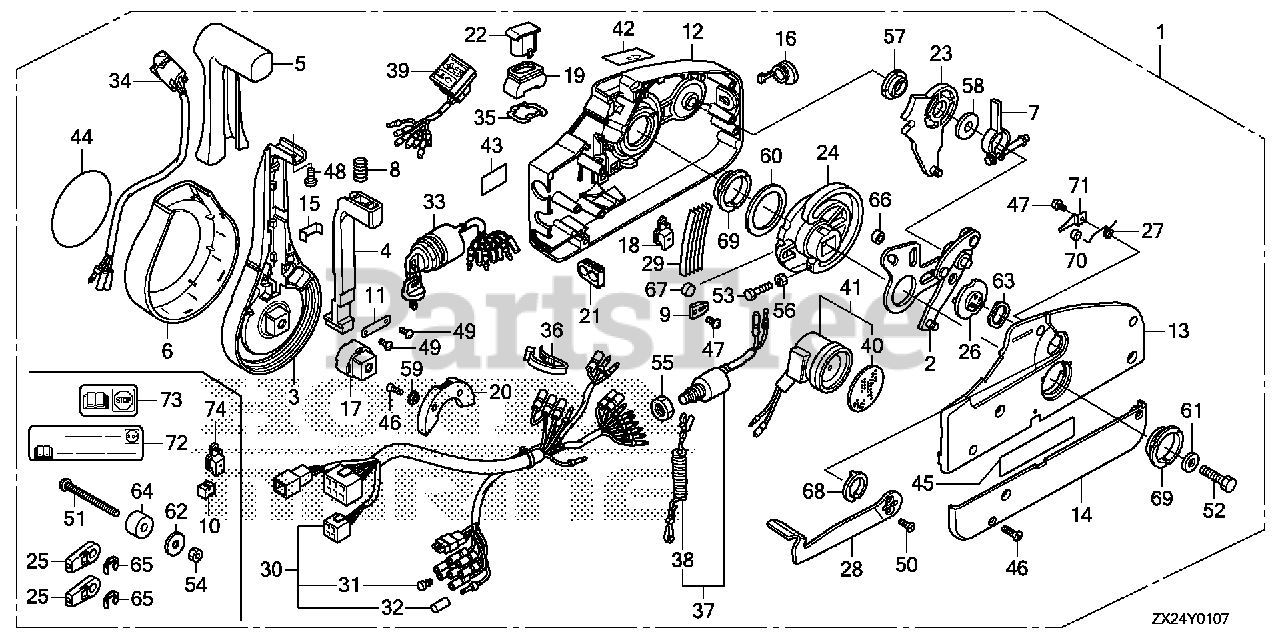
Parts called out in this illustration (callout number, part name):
1	BOX ASSY., REMOTE CONTROL (NHK MEC)
1	BOX ASSY., REMOTE CONTROL (TROLLING CONTROL)(NHK MEC)
2	PLATE ASSY.
3	LEVER, HAND
4	ARM, NEUTRAL LOCK
5	GRIP
6	COVER, LEVER
7	ARM ASSY., BRAKE
8	SPRING (2)
9	CLIP, DETENT
10	SPACER (1) (LOOSE PARTS)
11	BRACKET
12	HOUSING, FR.
13	HOUSING, RR.
14	PANEL, BACK
15	BRACKET, WIRE CLAMP
16	CAP, RUBBER
17	ADJUSTER
18	COVER, POWER TRIM-TILT WIRE
19	SEAL, RUBBER
20	HOLDER, NEUTRAL LOCK
21	GROMMET, WIRE (14)
22	CAP, TROLLING CONTROL SWITCH BLANK
23	GEAR ASSY., SHIFT
24	GEAR, DRIVE
25	TERMINAL, CABLE (LOOSE PARTS)
26	DRUM ASSY., FREE THROTTLE
27	SPRING (1)
28	LEVER, FREE THROTTLE
29	SPRING, DETENT
30	CABLE ASSY., REMOTE CONTROL (B)
31	PLUG, CONNECTOR (INNER)
32	PLUG, CONNECTOR (OUTER)
33	SWITCH ASSY., COMBINATION
34	SWITCH ASSY., POWER TRIM-TILT
35	PLATE, SWITCH
36	BAND, WIRE
37	SWITCH ASSY., EMERGENCY STOP
38	WIRE, EMERGENCY
39	LAMP ASSY., INDICATION
40	PLATE, TURN SIGNAL BUZZER
41	BUZZER, WARNING
42	MARK, FAST IDLE
43	MARK, EMERGENCY STOP (US)
44	MARK, EMBLEM
45	LABEL, SIGP
46	SCREW (5X18)
47	SCREW (4X6)
48	SCREW (5X10)
49	SCREW (4X10)
50	SCREW (5X12)
51	SCREW (6X90) (LOOSE PARTS)
52	BOLT (8X50)
53	BOLT (5X25)
54	NUT (6MM) (LOOSE PARTS)
55	NUT, HEX. (16MM)
56	NUT (5MM)
57	BEARING (1)
58	WASHER (3)
59	WASHER (4)
60	WASHER (5)
61	WASHER (8MM)
62	WASHER (7) (LOOSE PARTS)
63	WASHER, WAVE
64	SPACER (2) (LOOSE PARTS)
65	E-RING (6MM) (LOOSE PARTS)
66	ROLLER, DRIVE GEAR CAM
67	ROLLER
68	BEARING (2)
69	BEARING (3)
70	ROLLER, FREE THROTTLE
71	CLIP, ROLLER
72	MARK, EMERGENCY STOP (US) (LOOSE PARTS)
74	COVER, POWER TRIM-TILT WIRE (LOOSE PARTS)
